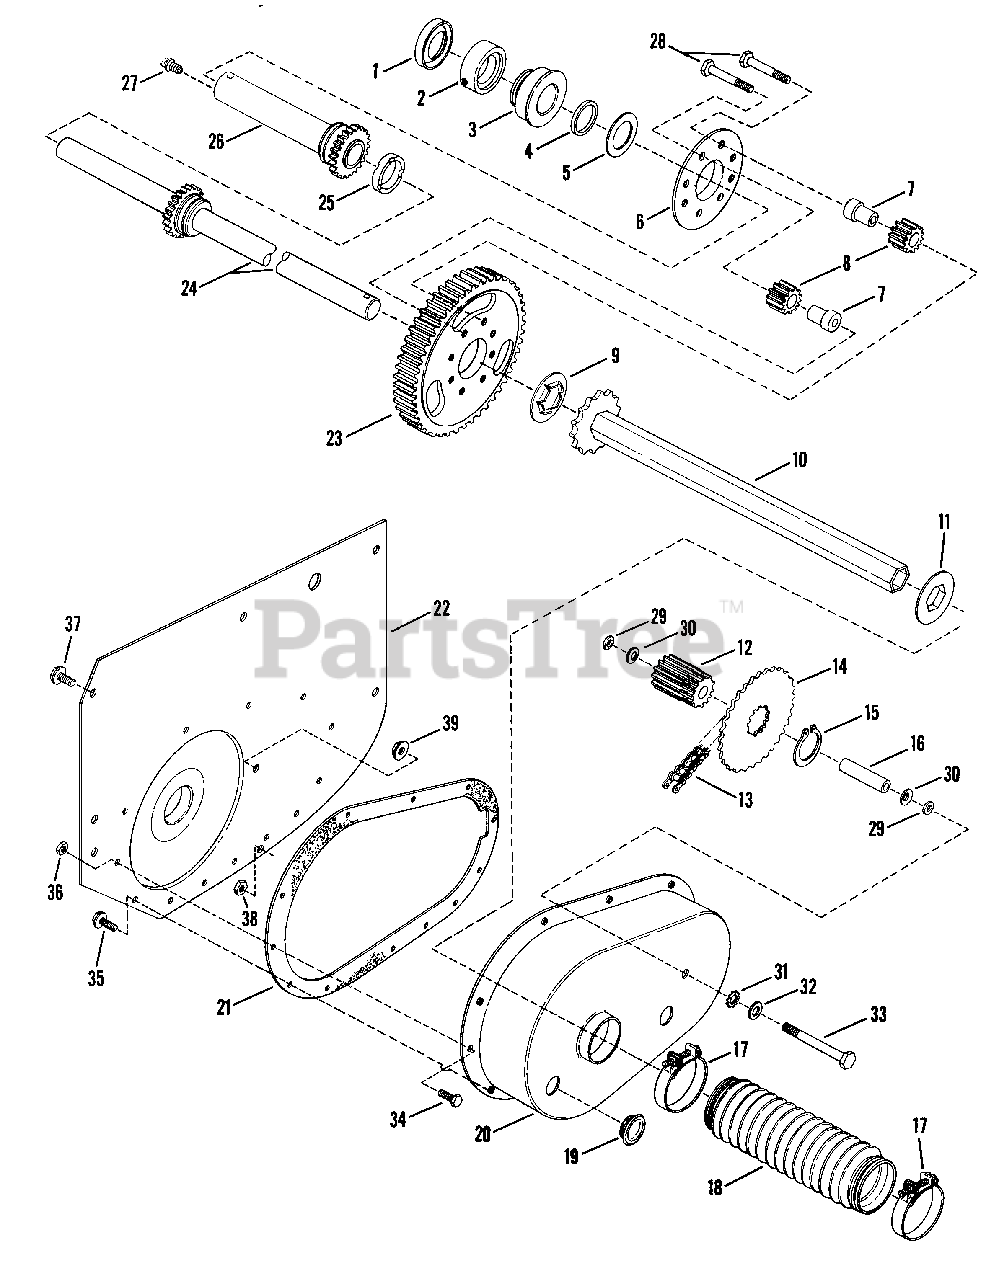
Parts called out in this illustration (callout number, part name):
1	SEAL, Oil
2	COLLAR, Lock
3	BEARING, Axle Right Hand Fender
4	SPACER, Short Axle
5	WASHER, Thrust
6	PLATE, Differential
7	SPACER, Pinion
8	PINION GEARS, Differential
9	WASHER, Thrust
10	ASSEMBLY, Drive Hex Tube
10A	ASSEMBLY, Drive Hex Tube
10B	ASSEMBLY, Drive Hex Tube
11	WASHER, Hex
12	GEAR, 11 Teeth, 10 Pitch
13	CHAIN, 46 Pitch (#35)
14	SPROCKET
15	RING, External Retaining
16	SPACER
17	CLAMP, Boot
18	BOOT, Oil Seal
19	PLUG, Oil Fill & Check
20	CASE, Transmission
21	GASKET, Transmission Case
22	FENDER, Right Hand
23	GEAR, 63 Teeth, 10 Pitch
24	AXLE, Long
25	SPACER, Differential (1.25" ID x .425 Wide)
26	AXLE, Short (DX)
26A	AXLE, Short (DX)
26B	AXLE, Short (DX)
27	FITTING, Lube
28	SCREW, 5/16-24 x 1-5/8" Special Lock Cap
29	O-RING, 5/16"
30	WASHER, 5/16" Belleville
31	WASHER, 5/16" External Tooth Lock
32	WASHER, 5/16" SAE Flat
33	BOLT, 5/16-24 x 2-5/8" (Idler)
34	SCREW, 1/4-20 x 5/8" Hex Head Cap, Grade 5
35	SCREW, 1/4-20 x 5/8" Self-Tapping )
36	NUT, 1/4-20 Hex Center Lock, Grade B or 5
37	SCREW, 5/16-18 x 5/8" Self-Tapping
38	NUT, 5/16-24 Hex
39	NUT, 5/16-24 Hex Flange Lock
